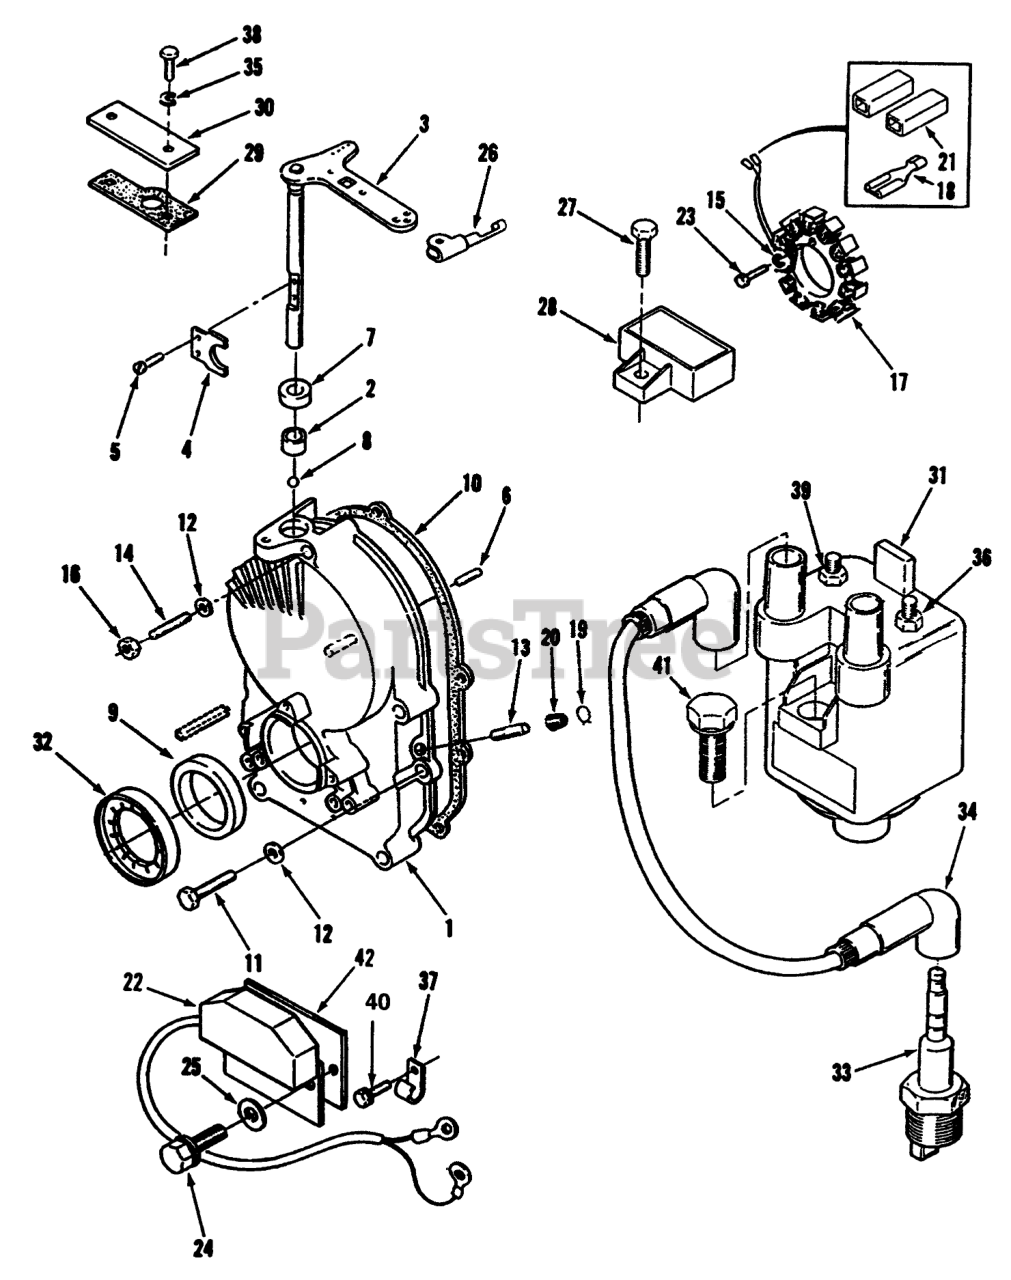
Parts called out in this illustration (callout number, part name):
1	Kit-Gearcase (Incl. Ref. #2-9, 13, 19, & 20)
2	BEARING
3	SHAFT AND ARM
5	SCREW-PAN HD
6	PIN-DOWEL
10	GEAR CASE MTG GASKET
11	Bolt
12	WASHER
13	TUBE-PORT, VACUUM
14	STUD-GEAR COVER
15	WASHER-LOCK, SPRING
16	NUT-GEAR COVER
17	KIT - STATOR
18	TERMINAL
19	CLAMP
20	CAP-FUEL OUTLET
21	BODY-TERM. CONNECTOR KIT
22	CONTROL-IGNITION
23	Screw-HH
24	Bolt
25	WASHER-LOCK
27	SCREW-HWH
28	REGULATOR
29	Gasket-Plate
30	PLATE-COVER
31	COIL-BATTERY IGNITION
32	ROTOR-IGNITION
33	SPARK PLUG
34	Wire-Plug
35	WASHER-FLAT
36	Nut
37	Clip
38	SCREW - CAP HEX HEAD
39	Nut
41	SCREW-HH
42	Insulator
